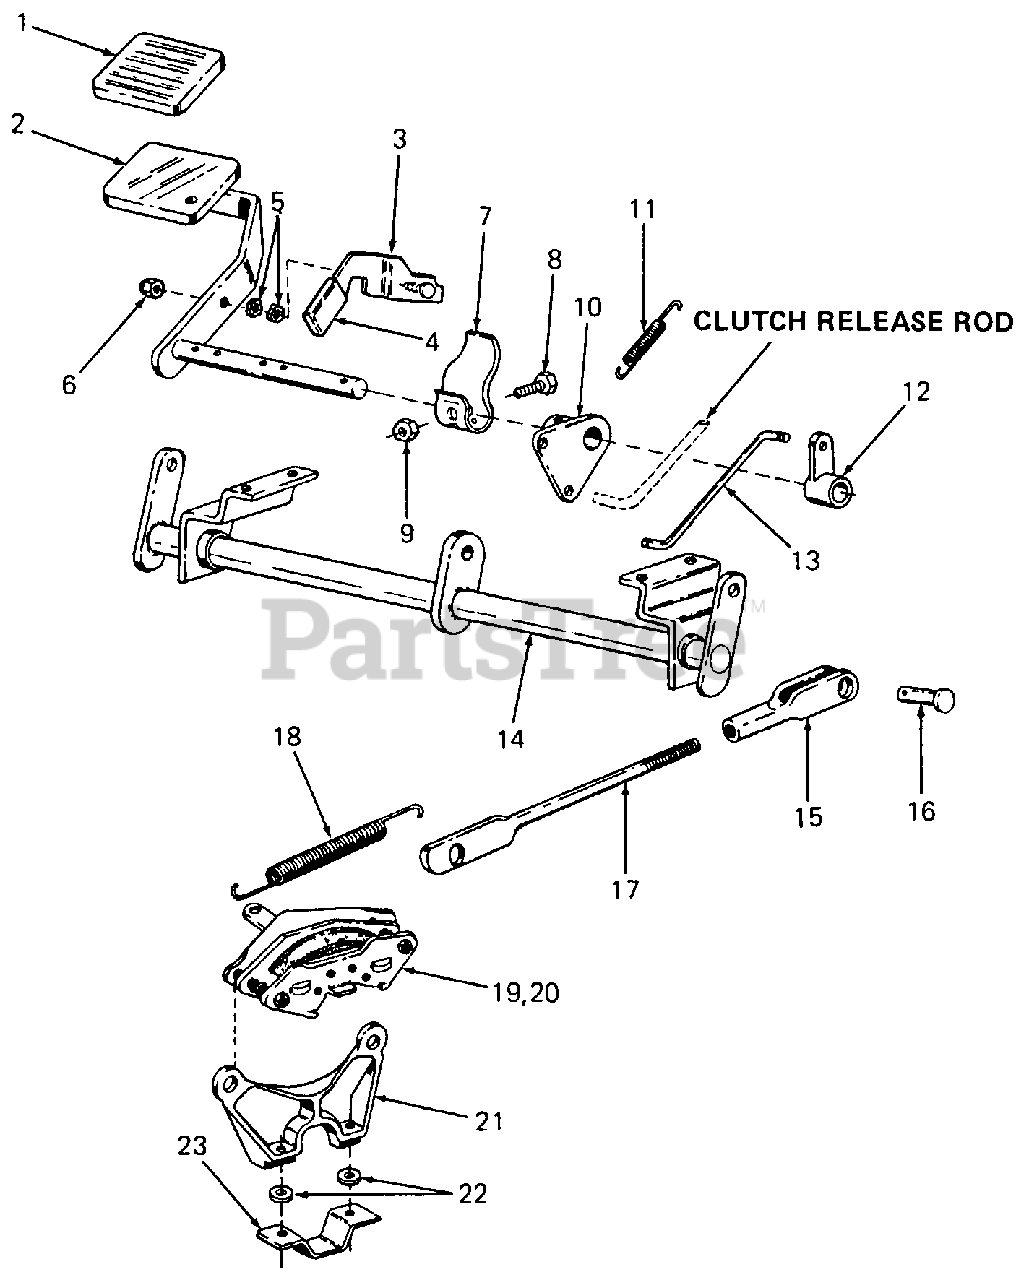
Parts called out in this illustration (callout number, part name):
1	Pad, Pedal
2	Pedal Assy, Brake & Clutch
5	Washer, Wave, 1/4 Dia
6	Nut, Hex Insert Lock, 1/4-20
7	Spring, Switch Operating
8	Screw, Hex Cap, 1/4-20 X .75 Lg GR5
9	Nut, Hex Center Lock, 1/4-20
11	Spring, Brake Return
13	Rod, Brake Lever
14	Shaft Assy, Brake
15	Clevis, Adjustment
16	Pin, Clevis, 3/8 Dia X 1.0 Lg
17	Rod, Brake
18	Spring, Extension
19	Brake Kit, LH - Caliper
20	Brake Kit, RH - Caliper
21	Bracket, Brake Mounting
22	Washer, Flat, .406 X .812 X .134 Thk
23	Bracket, Caliper Flange Mounting
